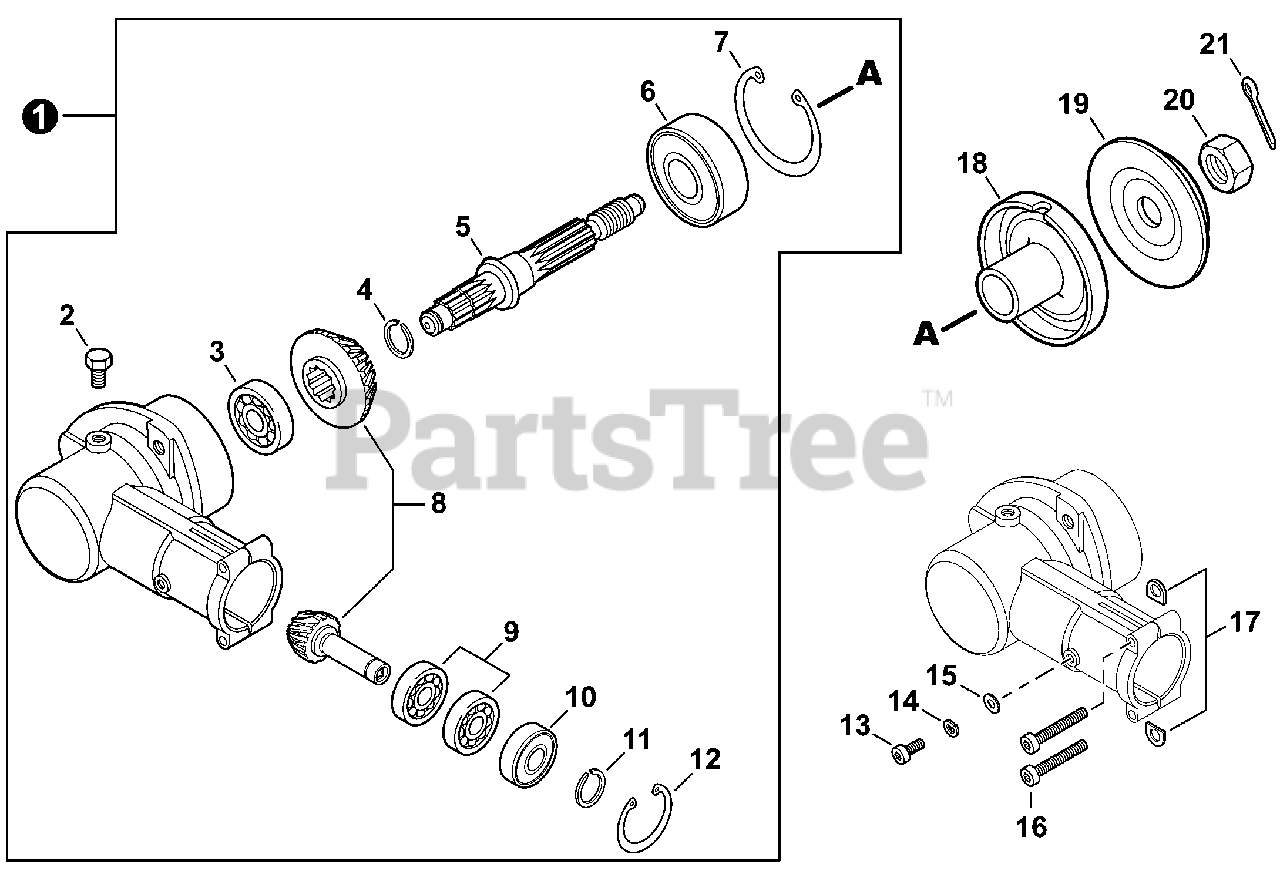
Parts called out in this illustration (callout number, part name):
1	GEAR CASE ASSY
2	BOLT M8×8
3	BEARING, BALL 629
4	RING, SNAP Ø12
5	SHAFT, GEAR
6	BEARING, BALL 6302
7	RING, SNAP Ø42
8	GEAR SET
9	BEARING, BALL 6900
10	BEARING, BALL 6900Z
11	RING, SNAP Ø10
12	RING, SNAP Ø22
13	BOLT, TORX 5×12
14	WASHER, SPRING 5
15	WASHER, FLAT 5.5×10×0.8
16	BOLT, TORX 5×25
17	D-WASHER
18	PLATE, ADAPTOR - UPPER
19	PLATE, ADAPTOR - LOWER
20	NUT 10×1.25 LH
21	PIN, COTTER 2×22
